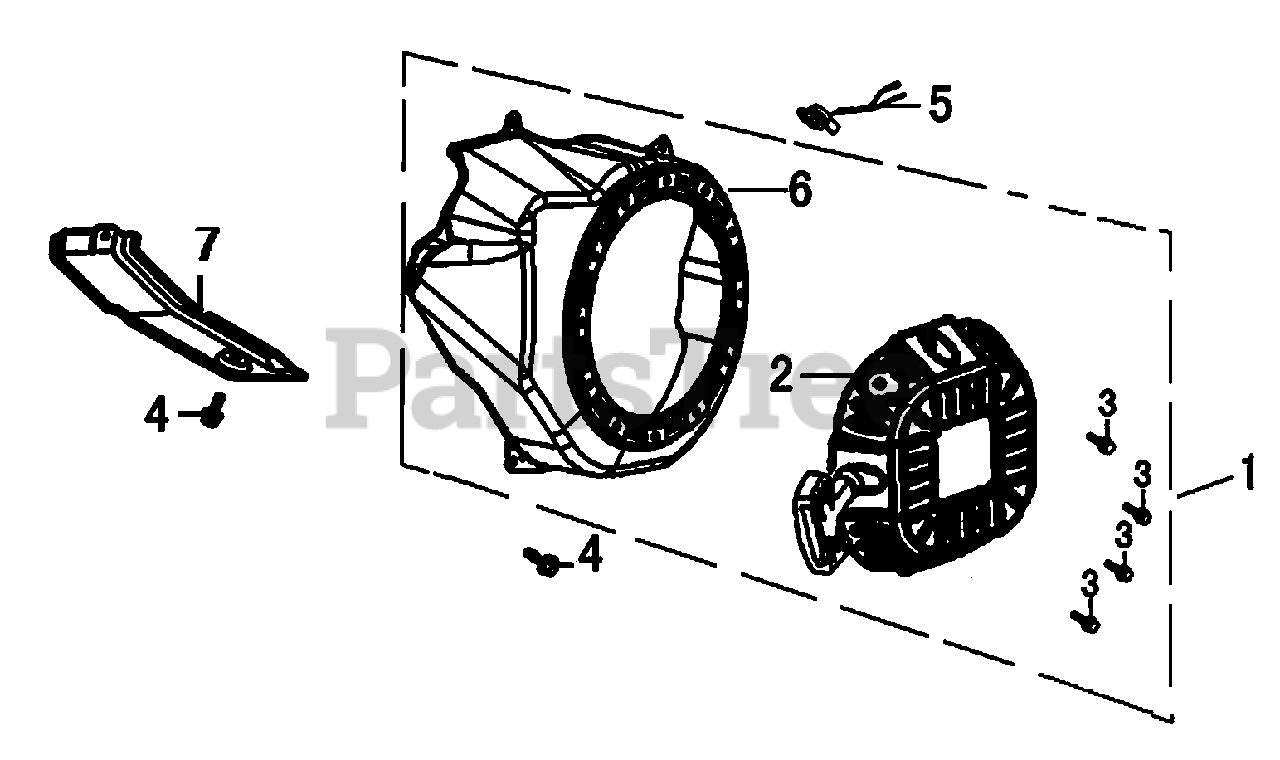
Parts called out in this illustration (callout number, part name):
1	STARTER, RECOIL W/ HOUSING
2	STARTER ASSY.
3	BOLT, FLANGE 6X8
4	BOLT, FLANGE 6X12
5	SWITCH ASSY., ENGINE STOP
6	HOUSING, BLOWER
